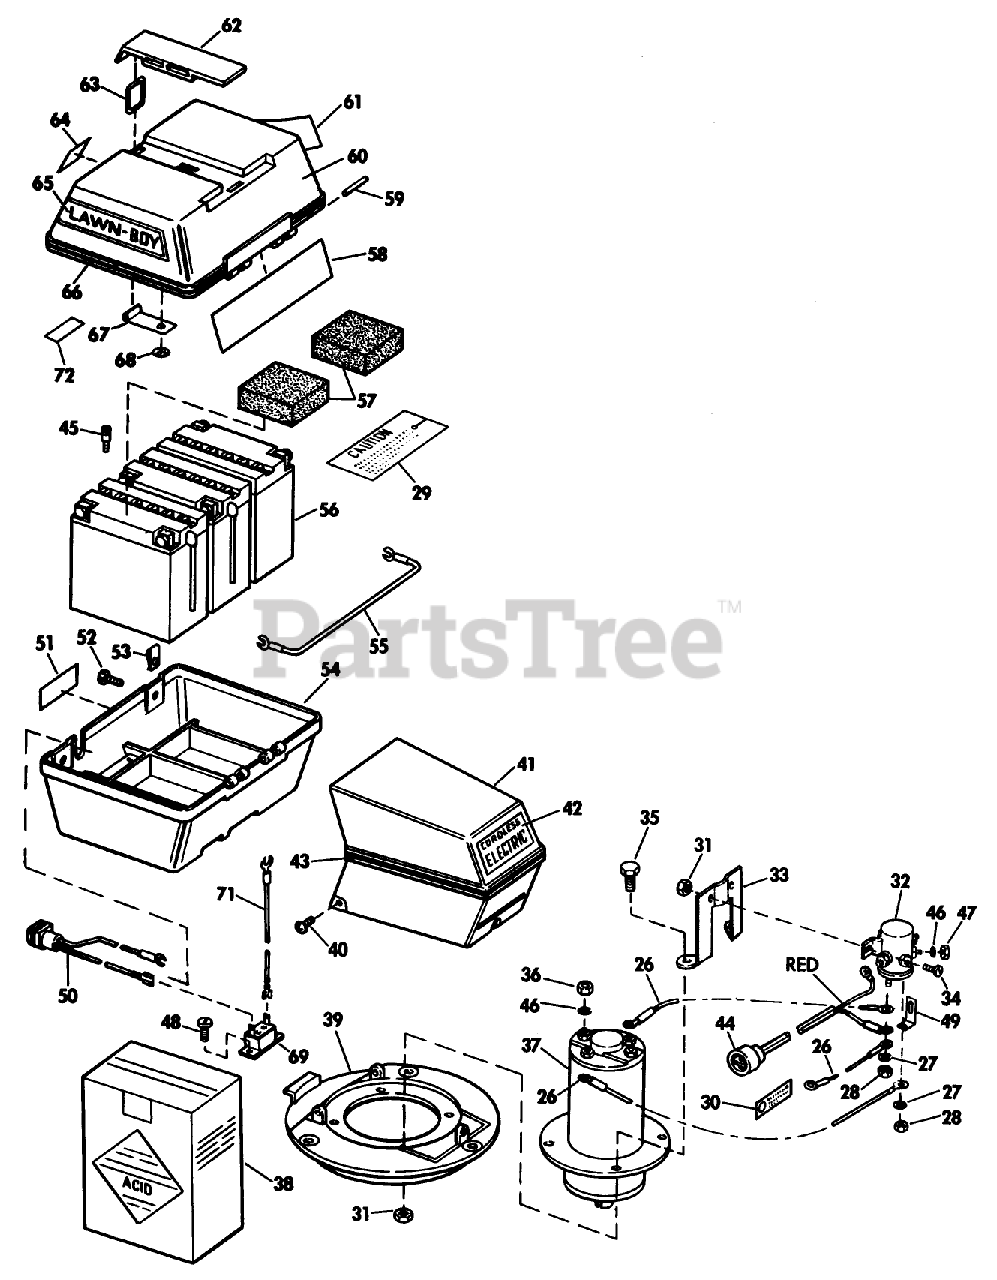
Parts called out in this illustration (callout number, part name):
28	Nut
30	Tag, Warning
31	LOCKNUT E
40	SCREW F
41	Motor Shroud Assy (5801)
47	Nut
49	Strip, Terminal
53	SPEED NUT ARDEN
54	Battery Box, Lower
60	Battery Box, Upper
62	Battery Box Handle
63	Support Ring
